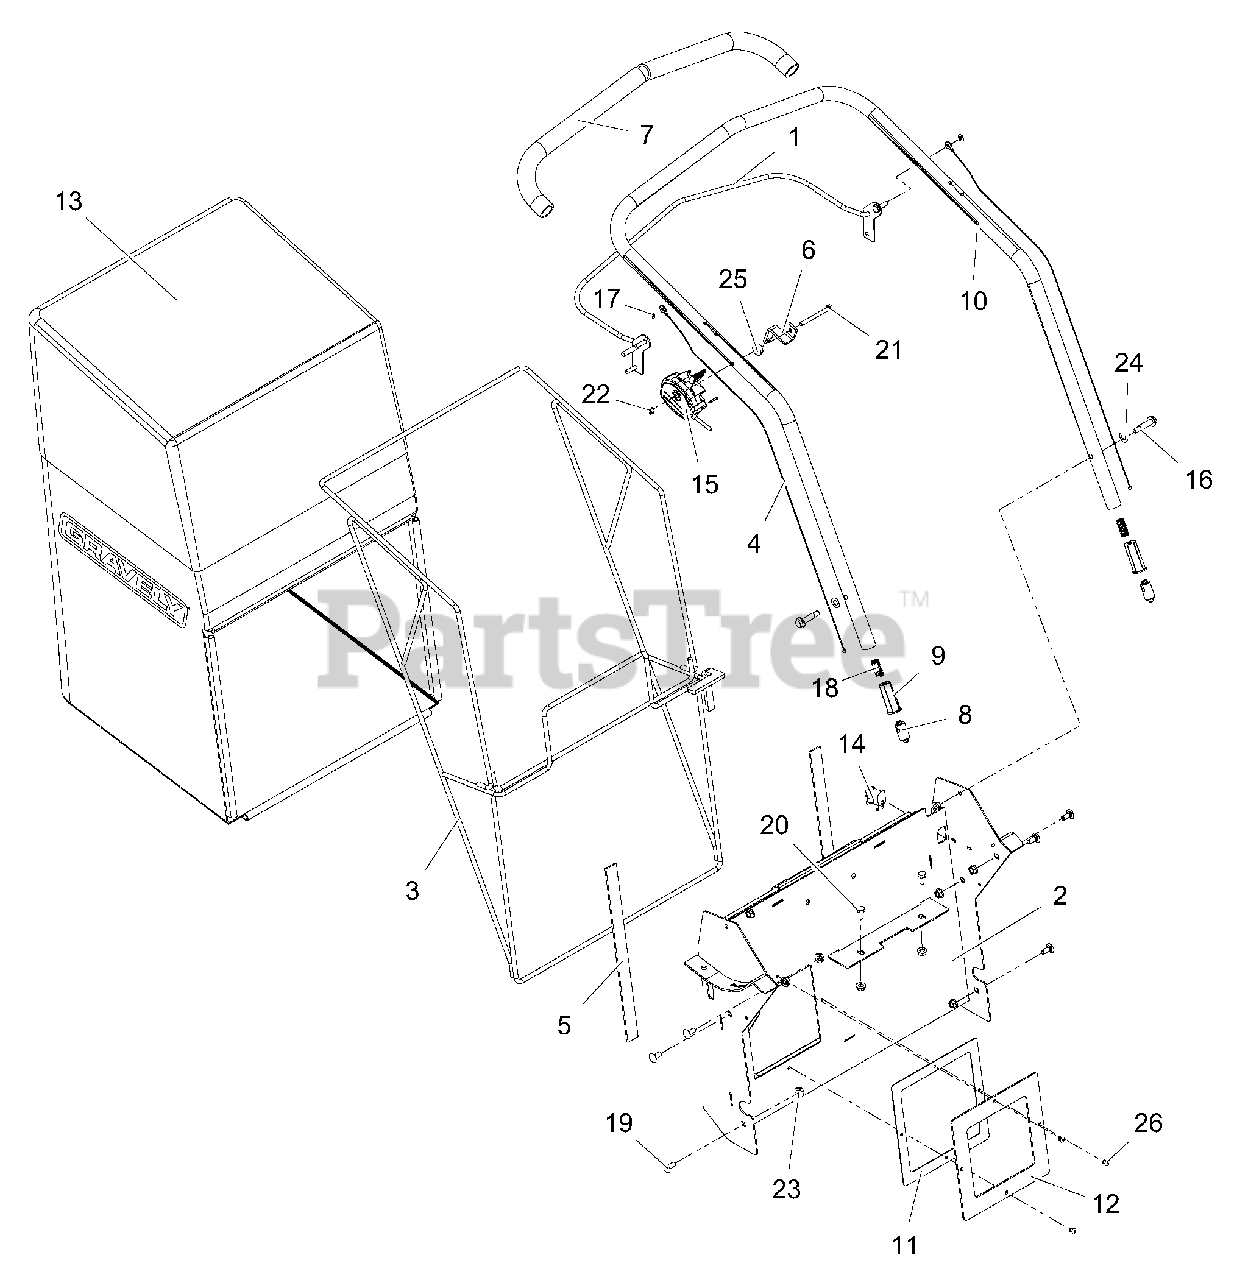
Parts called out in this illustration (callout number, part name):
1	WLDMT, BAIL,TRACTION APV
2	WLDMT, BAG BACKING PLATE
3	WLDMT, BAG FRAME - APV
4	CABLE, ADJUSTABLE HANDLEBAR
5	TAPE, FOAM - .12 x 1.00 VINYL
6	ANCHOR, CABLE
7	GRIP-HANDLEBAR, UPPER
8	PIN, LM HANDLEBAR LOCKING
9	HANDLEBAR ADJUSTMENT INSERT
10	HANDLEBAR, APV
11	PLATE, SEAL BACKER
12	SEAL, RUBBER
13	BAG, GRAVELY APV - FELT
14	SWITCH, SNAP MTG. N.C. W/BOOT
15	CABLE, THROTTLE /CHOKE 37.25"
16	BLT, SHLDR .50 x 1.30 x .38-16 GR5
17	NUT, PUSH .25 x .50 O.D.
18	SPRG, COMPRESSION
19	BLT-RDHDSQNK .31-18 x .75 G5 YWZC
20	BLT-HEX .31-18 x .625 GR5 YWZC
21	BLT-HEX .25-20 x 2.75 GR5 YWZC
22	NUT-LK-CTR .25-20 YWZC
23	NUT, LK-TOP-FLG .312-18 YWZC
24	WSHR-FL-STL .385 x .745 x .030 YWZC
25	WSHR-FL-STL .328 x .87 x .179 YWZC
26	RVT-POP .187 x .250 (#64) YWZC
